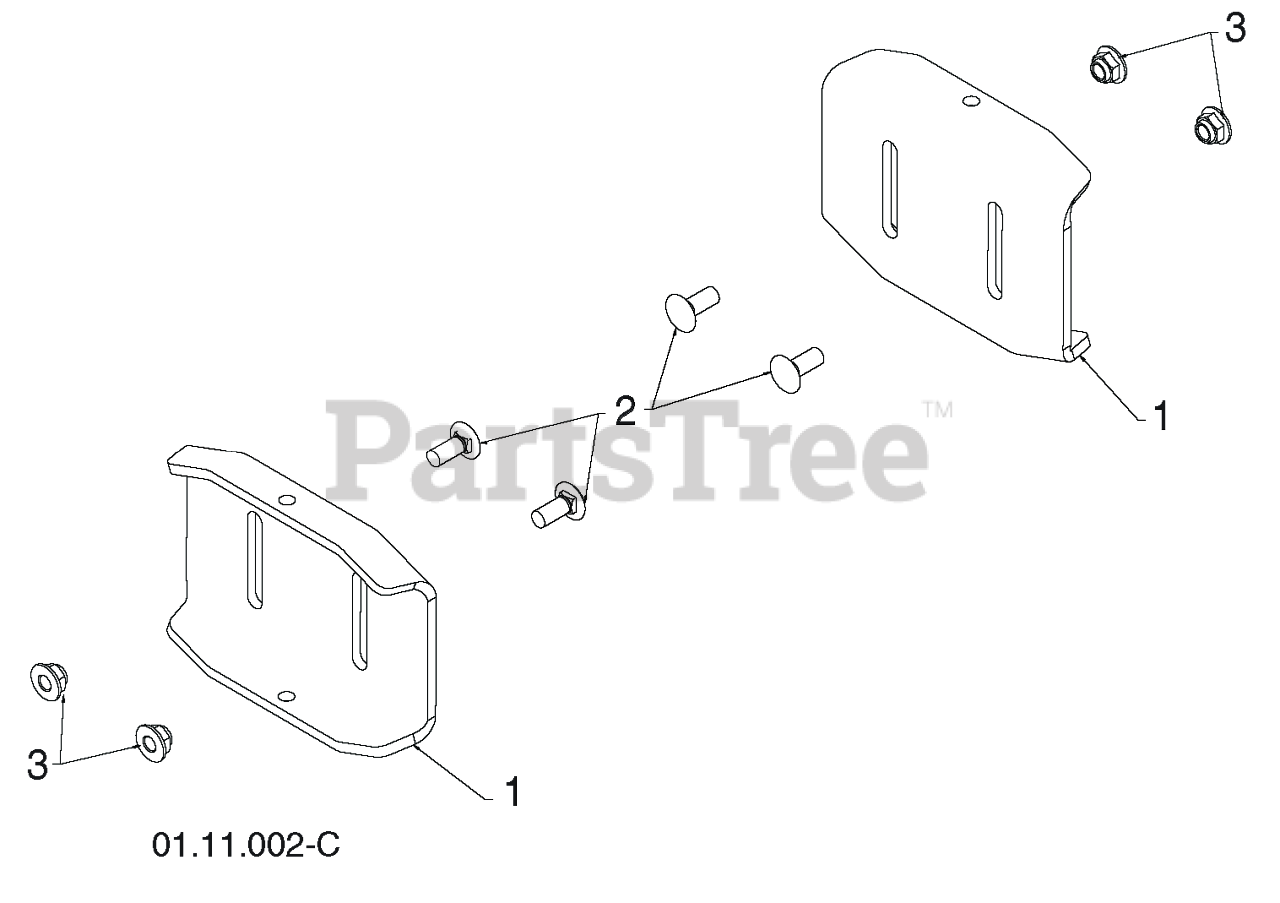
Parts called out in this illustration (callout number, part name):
1	SKID PLATE
2	BOLT
3	NUTNYLOK.FLRANGE.5/16-18
